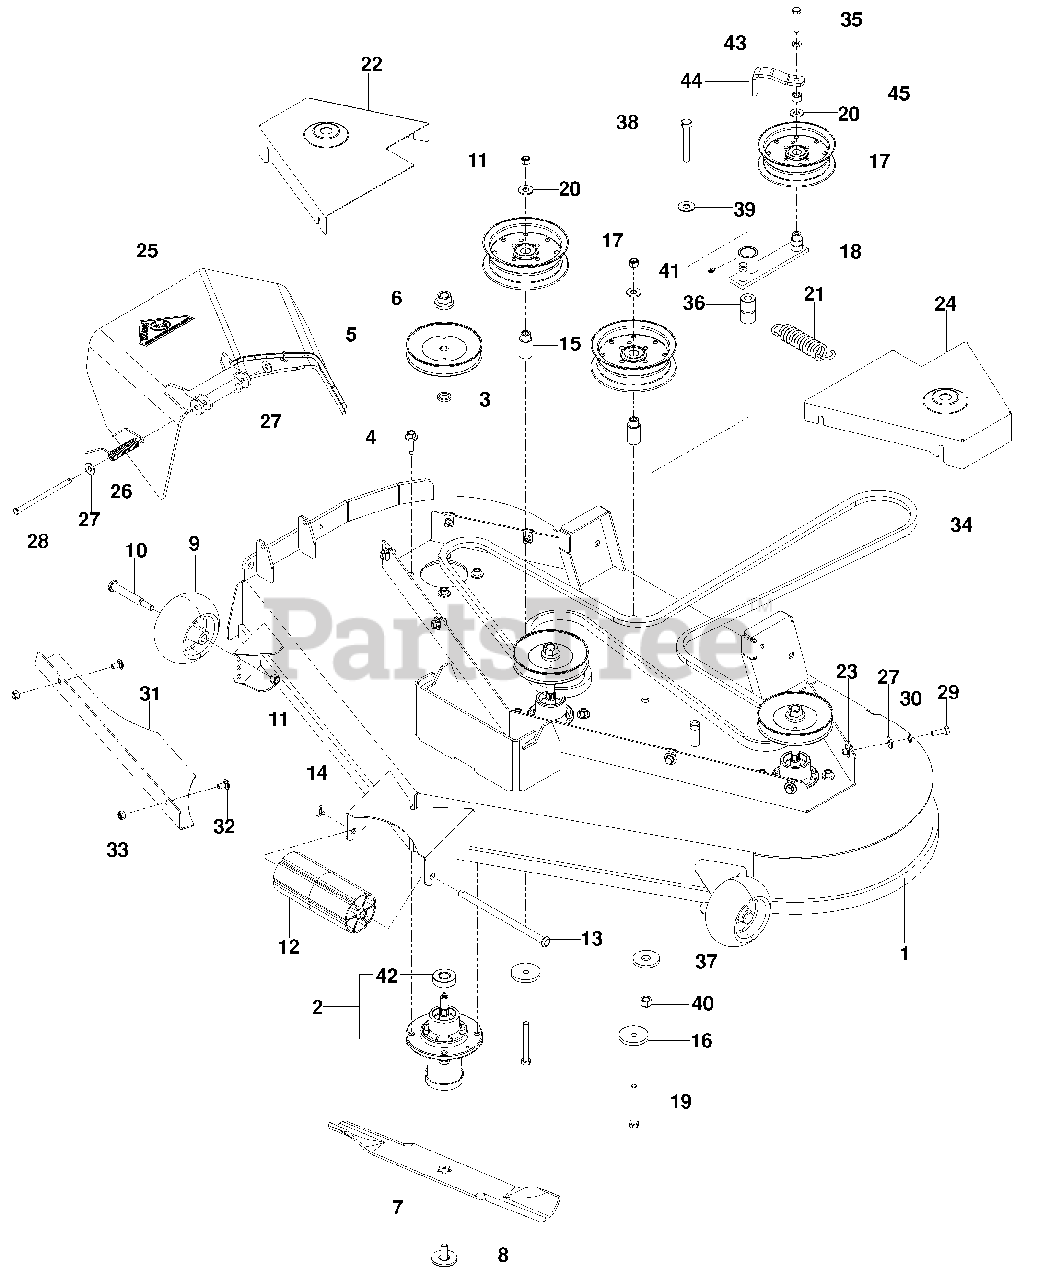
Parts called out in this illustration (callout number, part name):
1	DECK w/DECALS
2	HOUSING ASSY
3	WASHER, SPACER
4	SCREW 5/16 -18 x WSH HD
5	PULLEY
6	NUT 9/16 TOP CNTRLK
7	BLADE, 18"
8	BOLT 7/16 BLADE
9	WHEEL, GAUGE
10	BOLT 1/2-16 x 25/8 SHOULDER
11	NUT 3/8-16 HEX NYLOC
12	ROLLER, NOSE
13	ROD, ROLLER, NOSE
14	PIN, COTTER 1/8 x 3/4
15	BUSHING, IDLER
16	WASHER, HEAVY
17	PULLEY, IDLER
18	ARM, IDLER
19	HCS 3/8-16 x 3
20	WASHER 3/8 FLAT STD
22	BELT SHIELD, RT
23	RETAINER, U TYPE
24	BELT SHIELD, LT
25	CHUTE, DISCHARGE
26	SPRING, TORSION
27	WASHER 5/16 STD FLAT
28	PIN, CLEVIS 5/16
29	HCS 5/16-18 x 1
30	WASHER 5/16 SLW
31	PLATE, CONFINEMENT
32	RHSNB 5/16-18 x 5/8
33	NUT 5/16-18 HEX NYLOC
35	HCS 3/8-16 x 1 3/4
36	BUSHING, PIVOT
37	WASHER, SUPPORT
38	HCS 1/2-13 x 3 1/4
39	WASHER 1/2 STD FLAT
40	NUT 1/2 HEX NYLOC
41	ZERK
42	BEARING, BALL
43	WASHER, 3/8 SPLT LOCK
44	GUIDE, BELT
